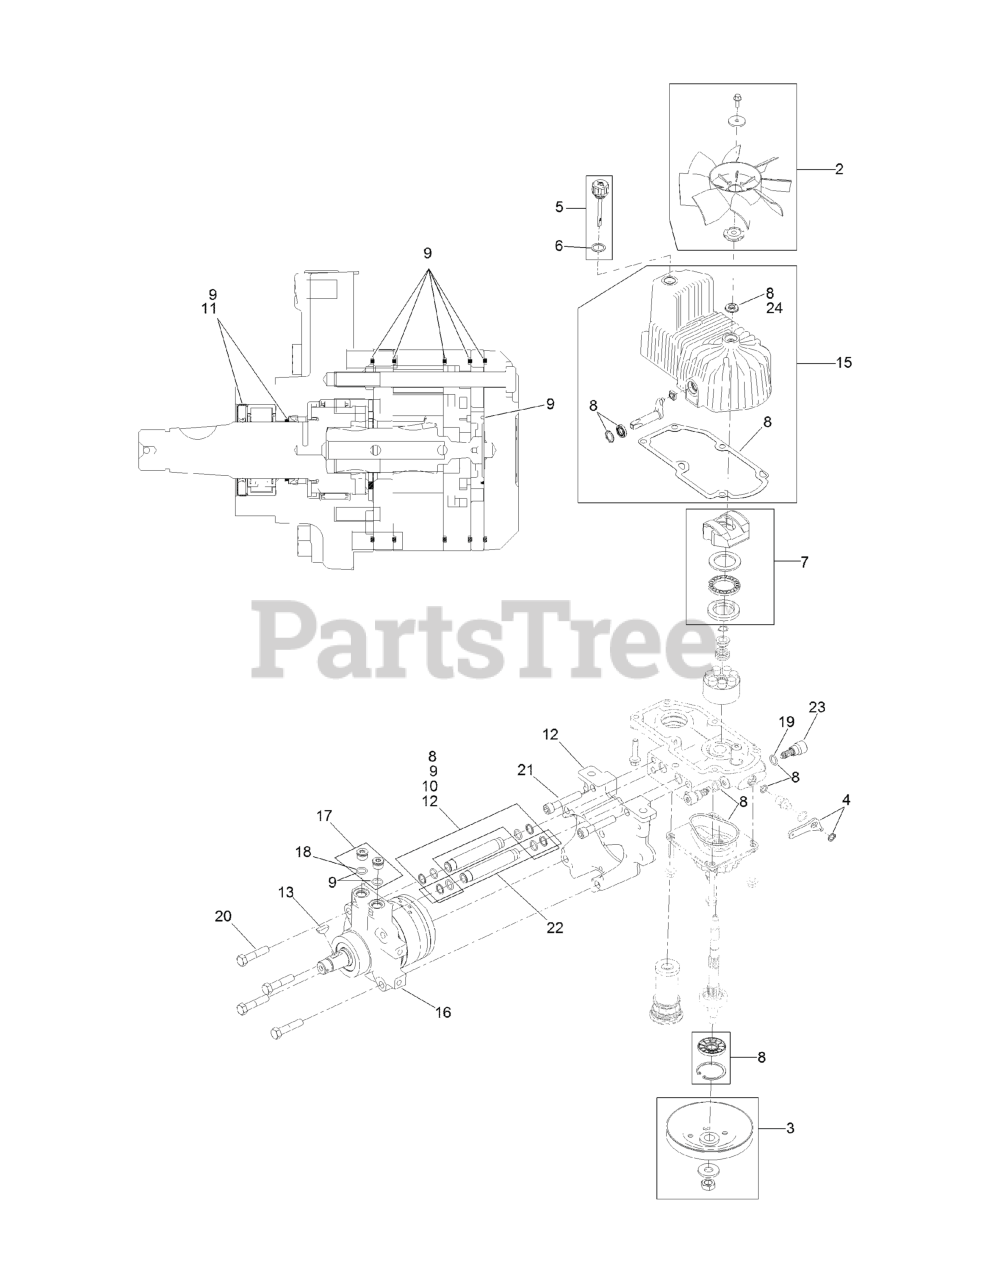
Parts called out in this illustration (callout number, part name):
2	FAN KIT
3	PULLEY KIT
4	HANDLE-BYPASS VALVE, HYDRO
5	DIPSTICK-HYDRO W/GASKET
6	GASKET-DIPSTICK, HYDRO
7	SWASH BLOCK KIT
8	PUMP SEAL KIT
9	MOTOR SEAL KIT
10	TUBE SEAL KIT
11	OUTPUT SHAFT SEAL KIT
12	NOSE CUP-UHT
13	KEY-WOODRUFF
15	HOUSING-HYDRO, LH
16	MOTOR-HYDRAULIC LH 240CC
17	MAGNETIC PLUGS SERVICE KIT
19	O-RING-CHECK VALVE
20	SCREW HH
21	SCREW-HSH
22	HYDRAULIC TUBE KIT
23	SHOCK VALVE, 12CC HYDRO
24	SEAL-FAN DRIVE
25	PULLER-PULLEY
26	ROTATING KIT
